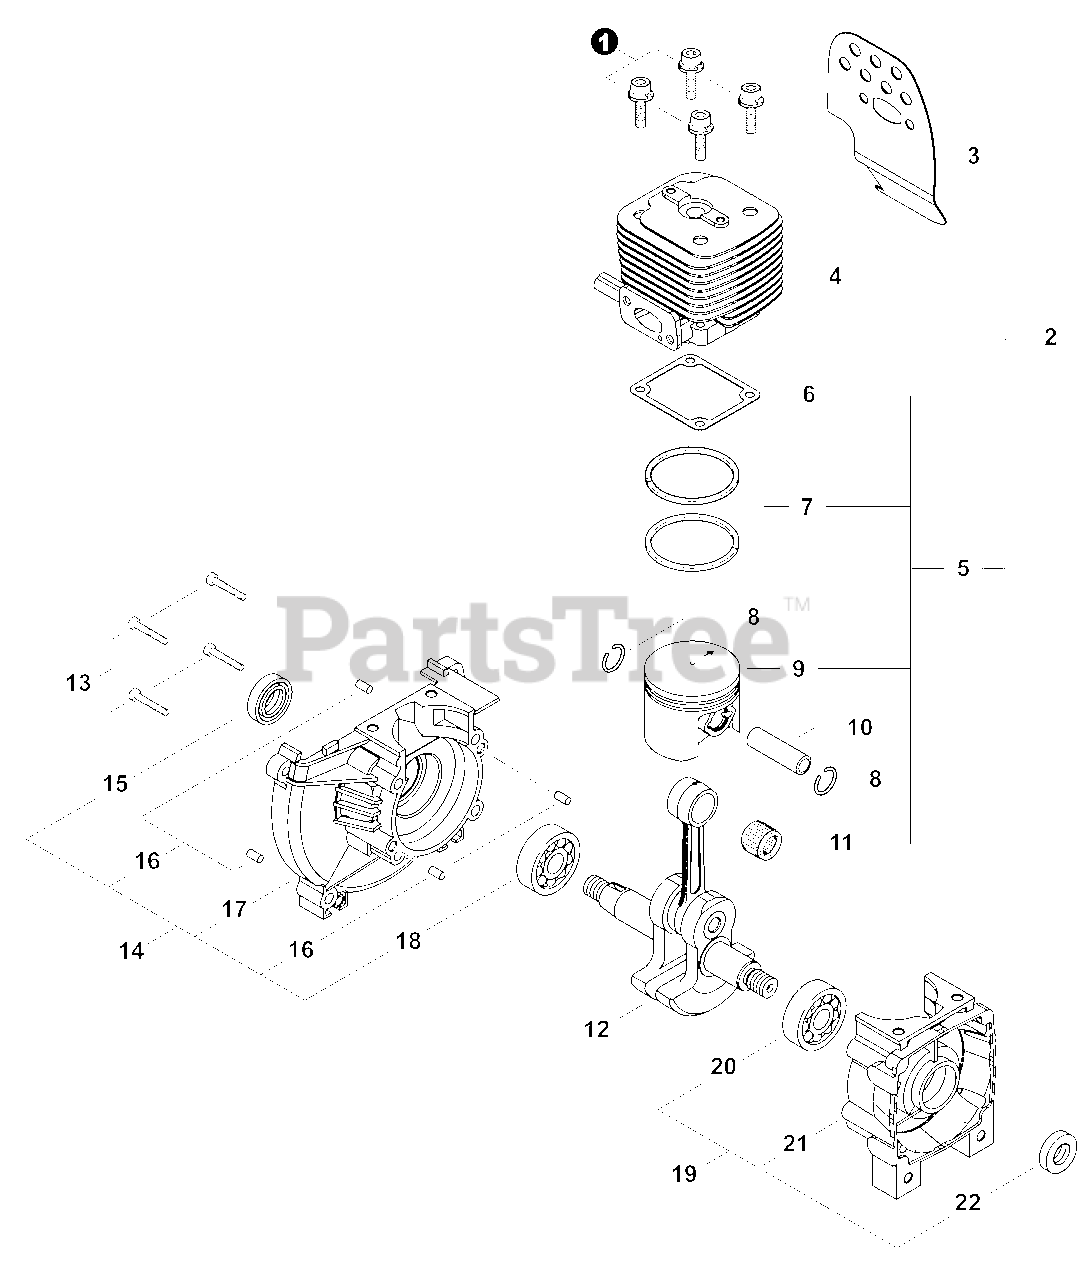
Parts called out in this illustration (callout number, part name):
1	BOLT M5x25
2	REPAIR KIT, ENGINE
3	HEAT SHIELD, EXHAUST
4	CYLINDER
5	PISTON KIT
6	GASKET, CYLINDER
7	RING, PISTON
8	RING, SNAP
9	PISTON
10	PIN, PISTON
11	BEARING, NEEDLE
12	CRANKSHAFT
13	BOLT 5x30
14	CRANKCASE ASSY, M
15	SEAL, OIL 16
16	PIN, LOCATING 5x10
17	CRANKCASE M
18	BEARING, BALL 6202 C3
19	CRANKCASE ASSY, S
20	BEARING, BALL 6202 C3
21	CRANKCASE S
22	SEAL, OIL 16
